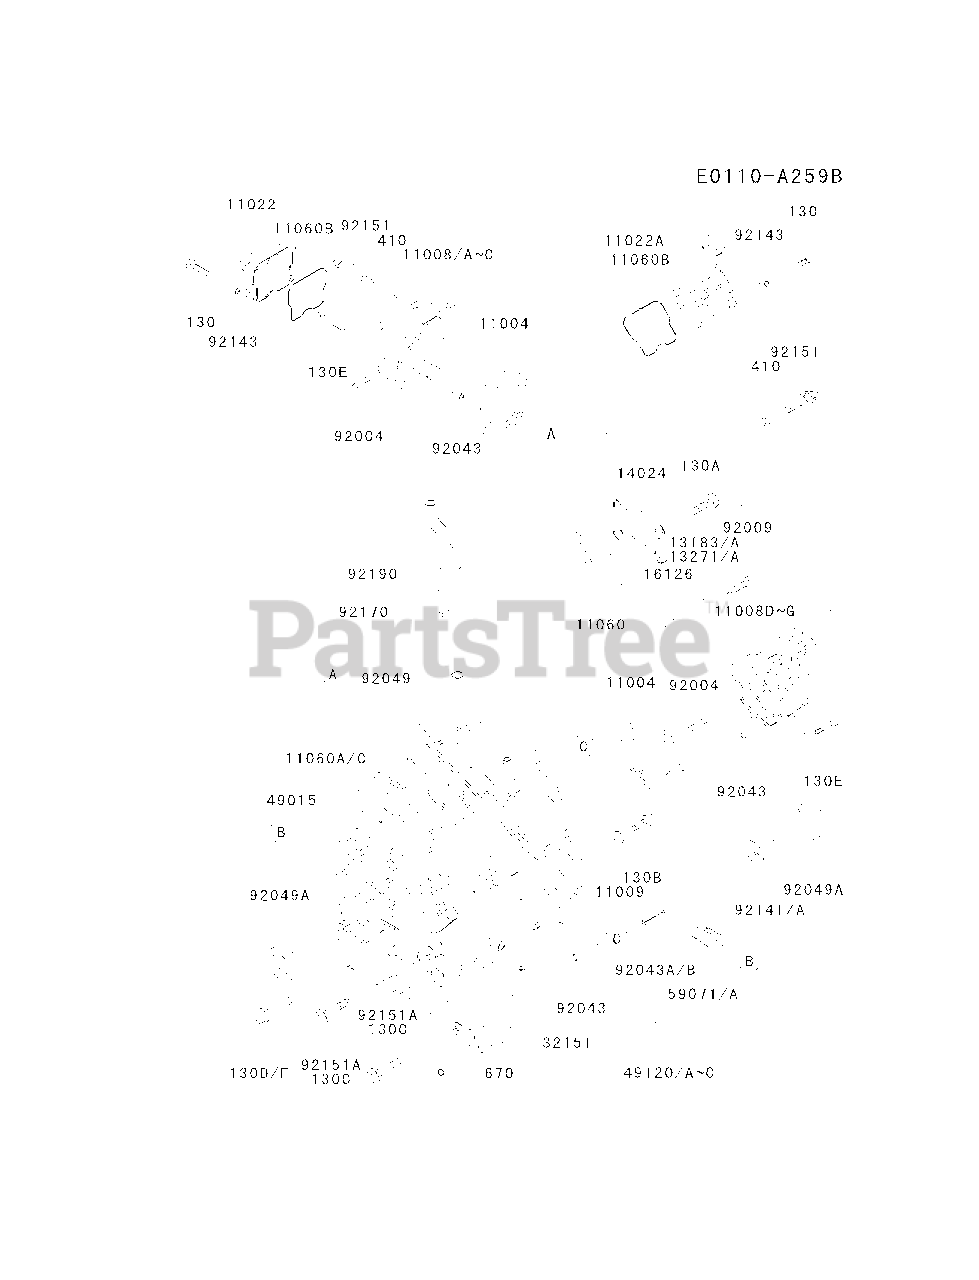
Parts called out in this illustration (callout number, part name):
130	BOLT-FLANGED
130A	BOLT-FLANGED
130B	BOLT-FLANGED
130C	BOLT-FLANGED
130D	BOLT-FLANGED
130E	BOLT-FLANGED
410	W-PLAIN-S
92049A	SEAL-OIL
